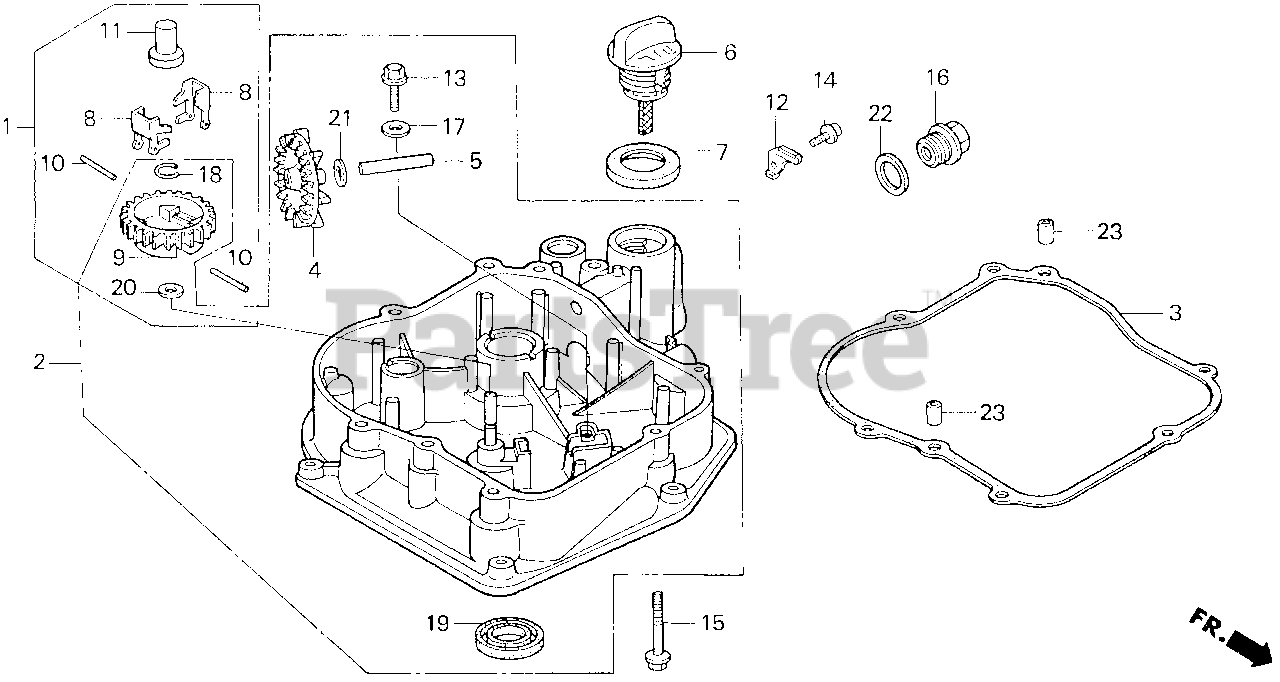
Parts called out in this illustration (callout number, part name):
1	GOVERNOR KIT (STD)
2	PAN ASSY., OIL
3	GASKET, CASE COVER
4	SLINGER, OIL
5	SHAFT, OIL SLINGER
6	CAP, OIL FILLER
7	GASKET, OIL FILLER CAP
8	WEIGHT, GOVERNOR
9	HOLDER, GOVERNOR WEIGHT
10	PIN, GOVERNOR WEIGHT
11	SLIDER, GOVERNOR
12	STOPPER, CABLE
13	BOLT, FLANGE (5X16)
14	BOLT, FLANGE (6X12) (CT200)
15	BOLT, FLANGE (6X28)
16	BOLT, DRAIN PLUG (20MM)
17	WASHER (6MM)
18	CLIP, GOVERNOR HOLDER
19	OIL SEAL (20X34X6)
20	WASHER, PLAIN (6MM)
21	WASHER, PLAIN (5MM)
22	WASHER, DRAIN PLUG (20MM)
23	PIN A, DOWEL (8X14)
